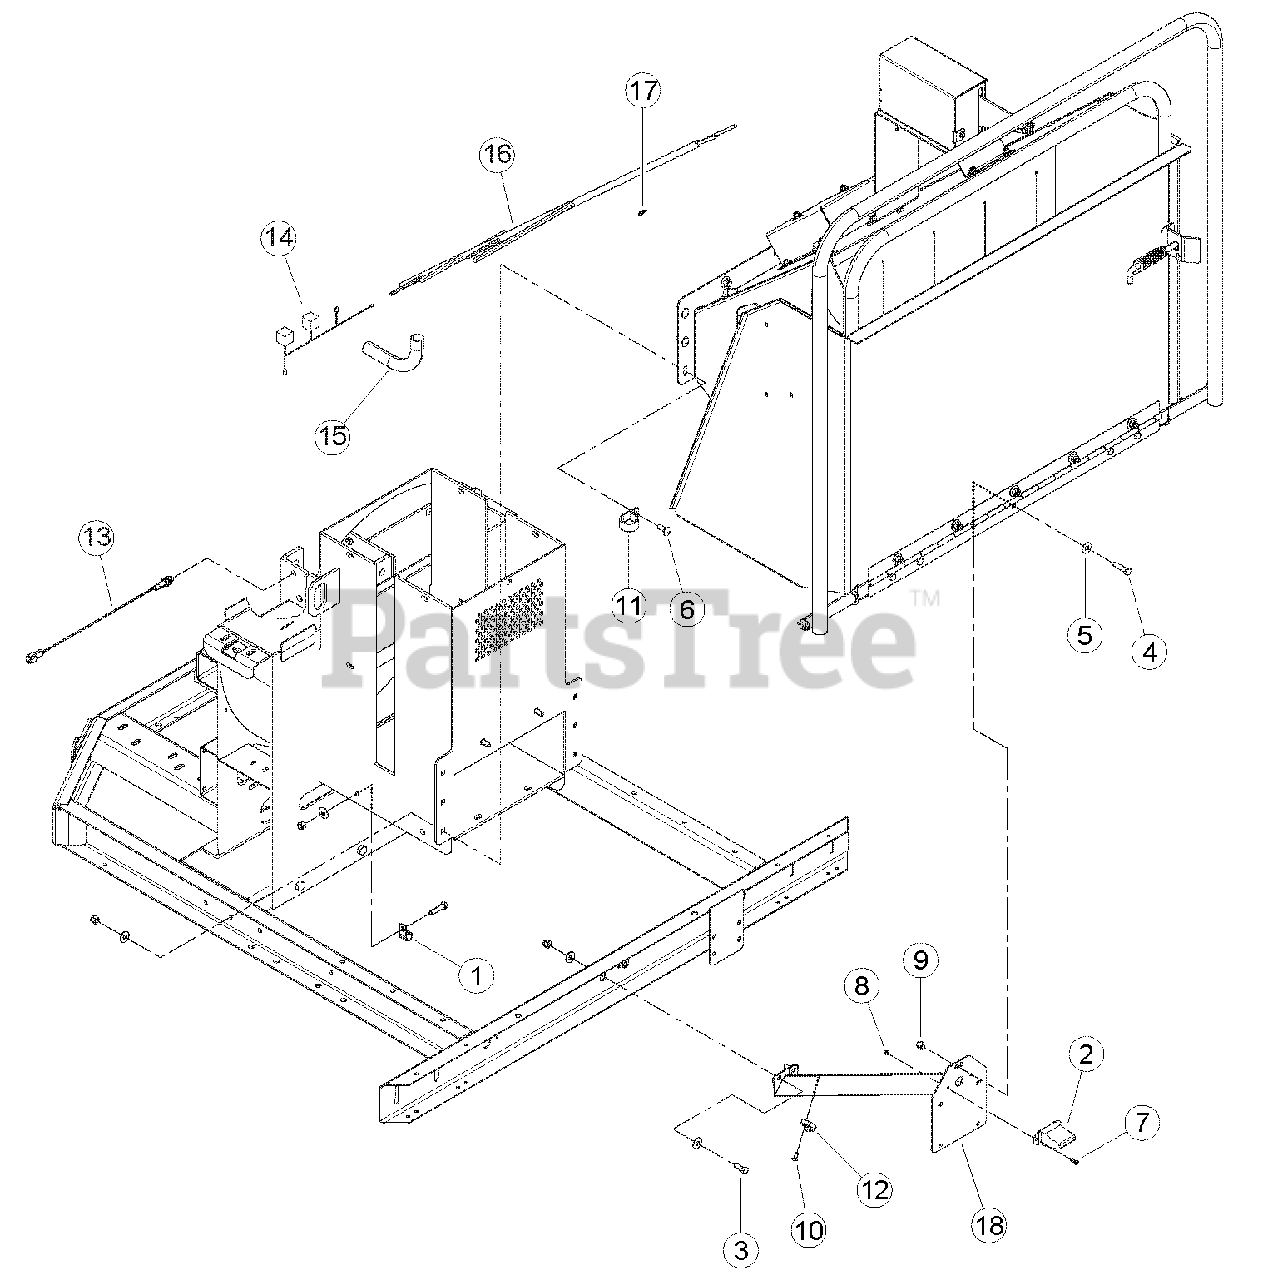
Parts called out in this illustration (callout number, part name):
1	CLAMP, 9/16 COATED
2	LIGHT, LICNESE PLATE
3	BOLT, 3/8 NC X 1 HEX HD GR5 ZP
4	BOLT, 3/8 NC X 1-1/2 HEX HD
5	WASHER, 3/8 FLAT ZP
6	BOLT, 3/8 X 1 CRG
7	SCREW, #10 X 3/4 HEX TAP SC
8	NUT, 8-32 NYLOCK
9	NUT, 3/8 NE NYLOCK ZP
10	RIVET, AL BLIND 1/4 X 3/4 DOME HEAD
11	CLAMP, 1-9/16 COATED
12	CLAMP, CABLE MOUNT
13	SENSOR, PROXIMITY
14	HARNESS, CHIPPER SAFETY RELAY
15	SLEEVING, BRAIDED ELECTRICAL HARNESS
16	HARNESS, 6 IN. GAS-PLUS 1
17	PLUG, JUMPER HARNESS
18	WELDMENT, CHUTE SUPPORT
